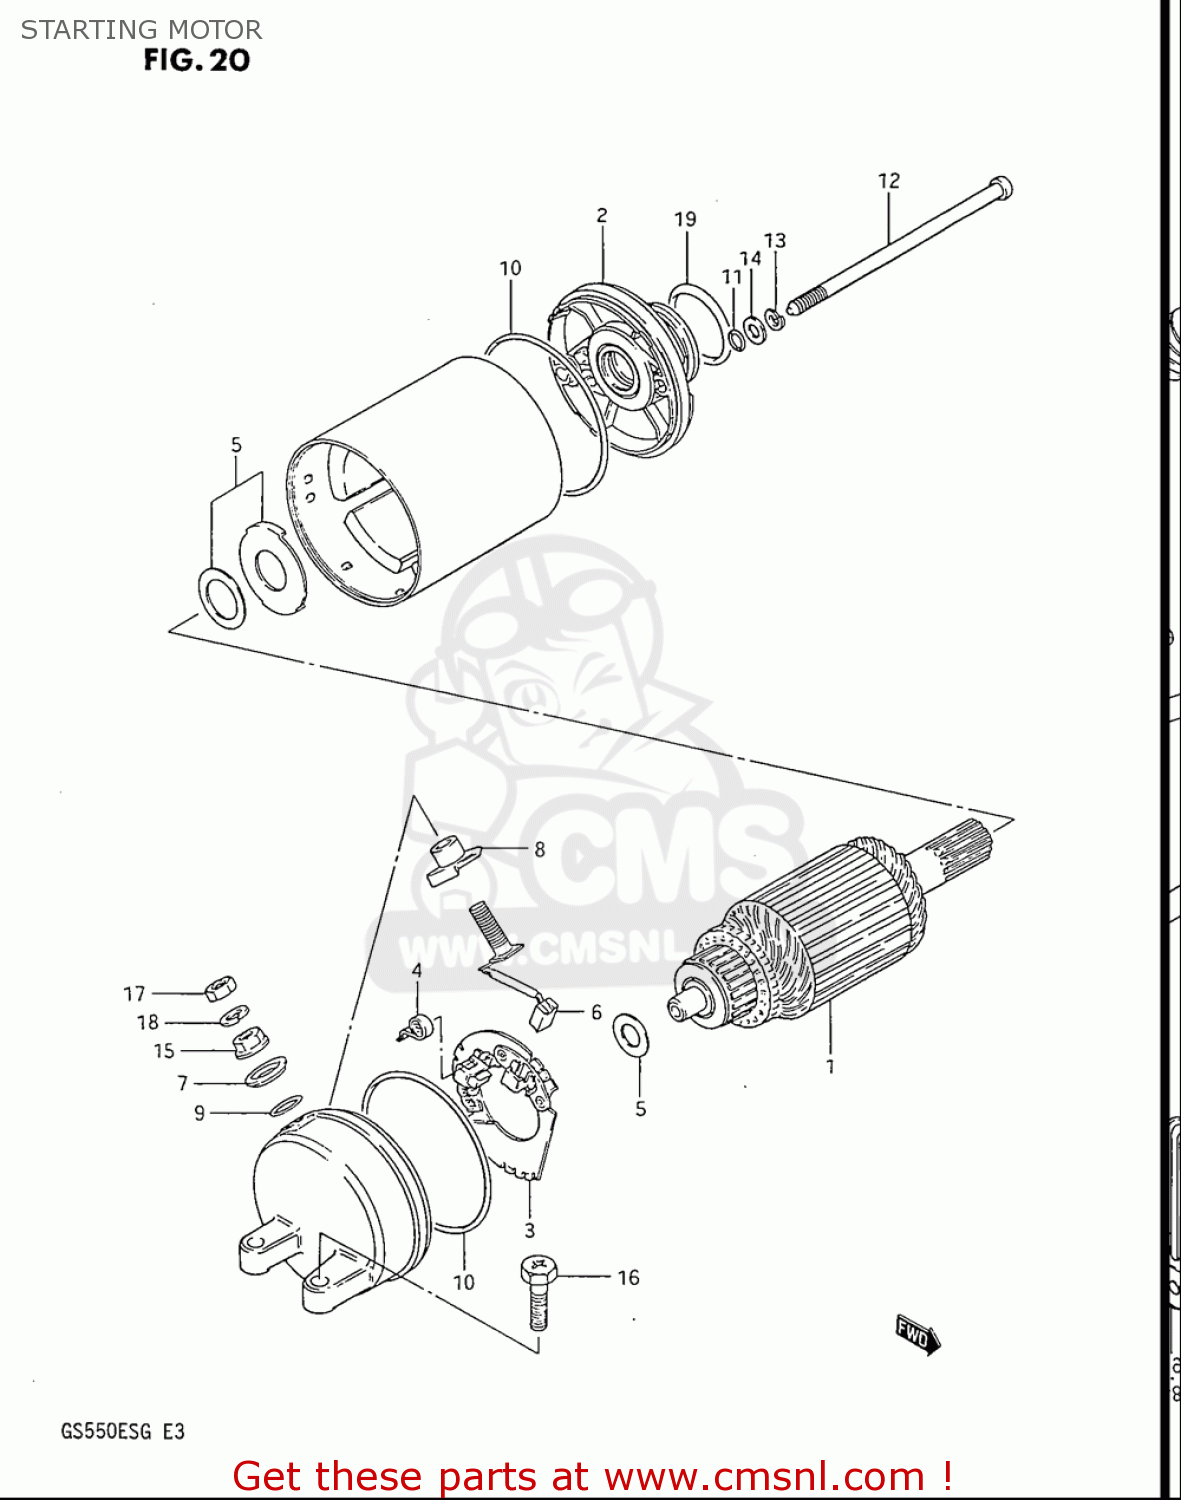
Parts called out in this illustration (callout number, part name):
1	ARMATURE
2	BRACKET SET,STARTING MOTOR
3	HOLDER,BRUSH
4	SPRING
5	SHIM SET,STARTING MOTOR
6	BRUSH SUB ASSY,STARTING MOTOR
7	BUSHING
8	BUSH,B
9	O RING
10	O RING
11	O RING
12	BOLT
13	WASHER,LOCK
14	WASHER
15	NUT
16	BOLT
17	NUT
18	WASHER,LOCK
19	O RING(D:3,ID:24.5)
